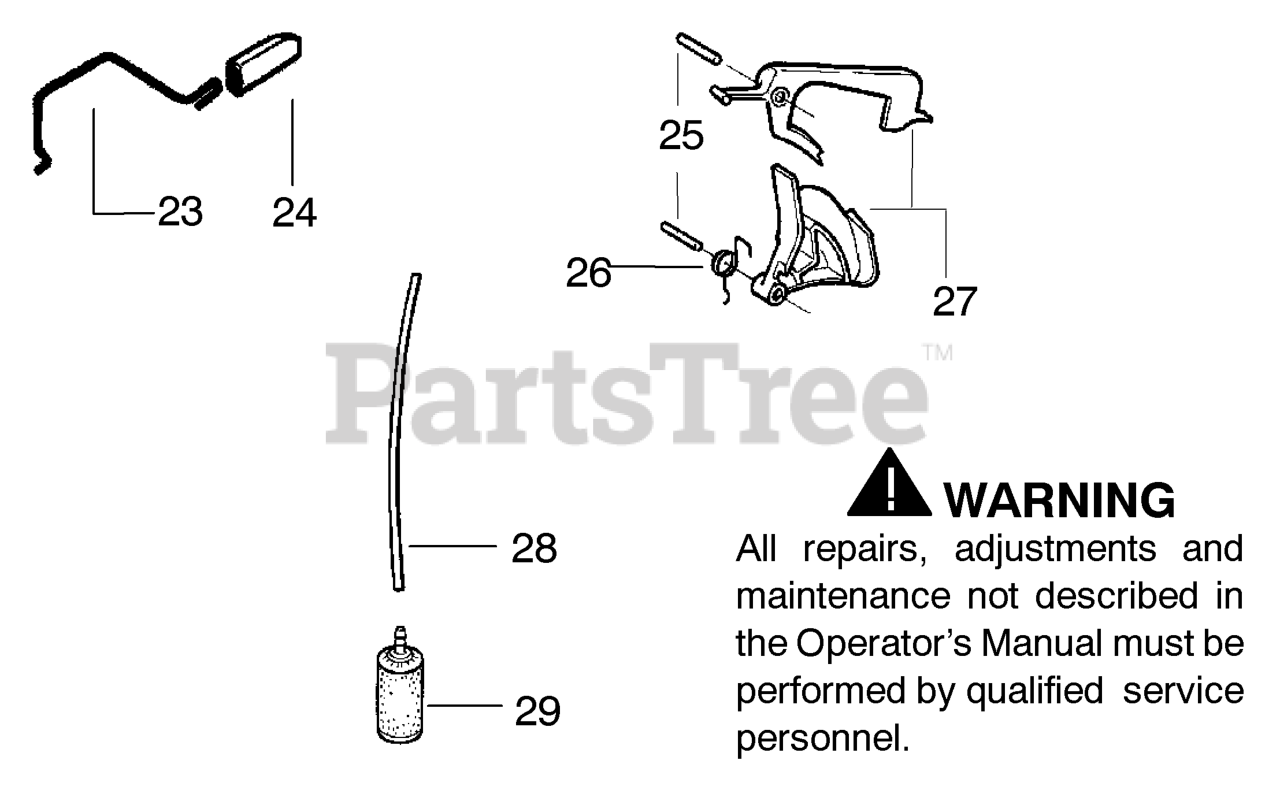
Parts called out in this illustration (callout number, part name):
23	THROTTLE SHAFT 36/41
24	THROTTLE ACTUATOR 36/41
25	PIN,TRIGGER 36/41
26	TRIGGER SPRING 36/41
27	THROTTLE TRIGGER-KIT
28	HOSE. FUEL
29	FUEL PICK-UP
